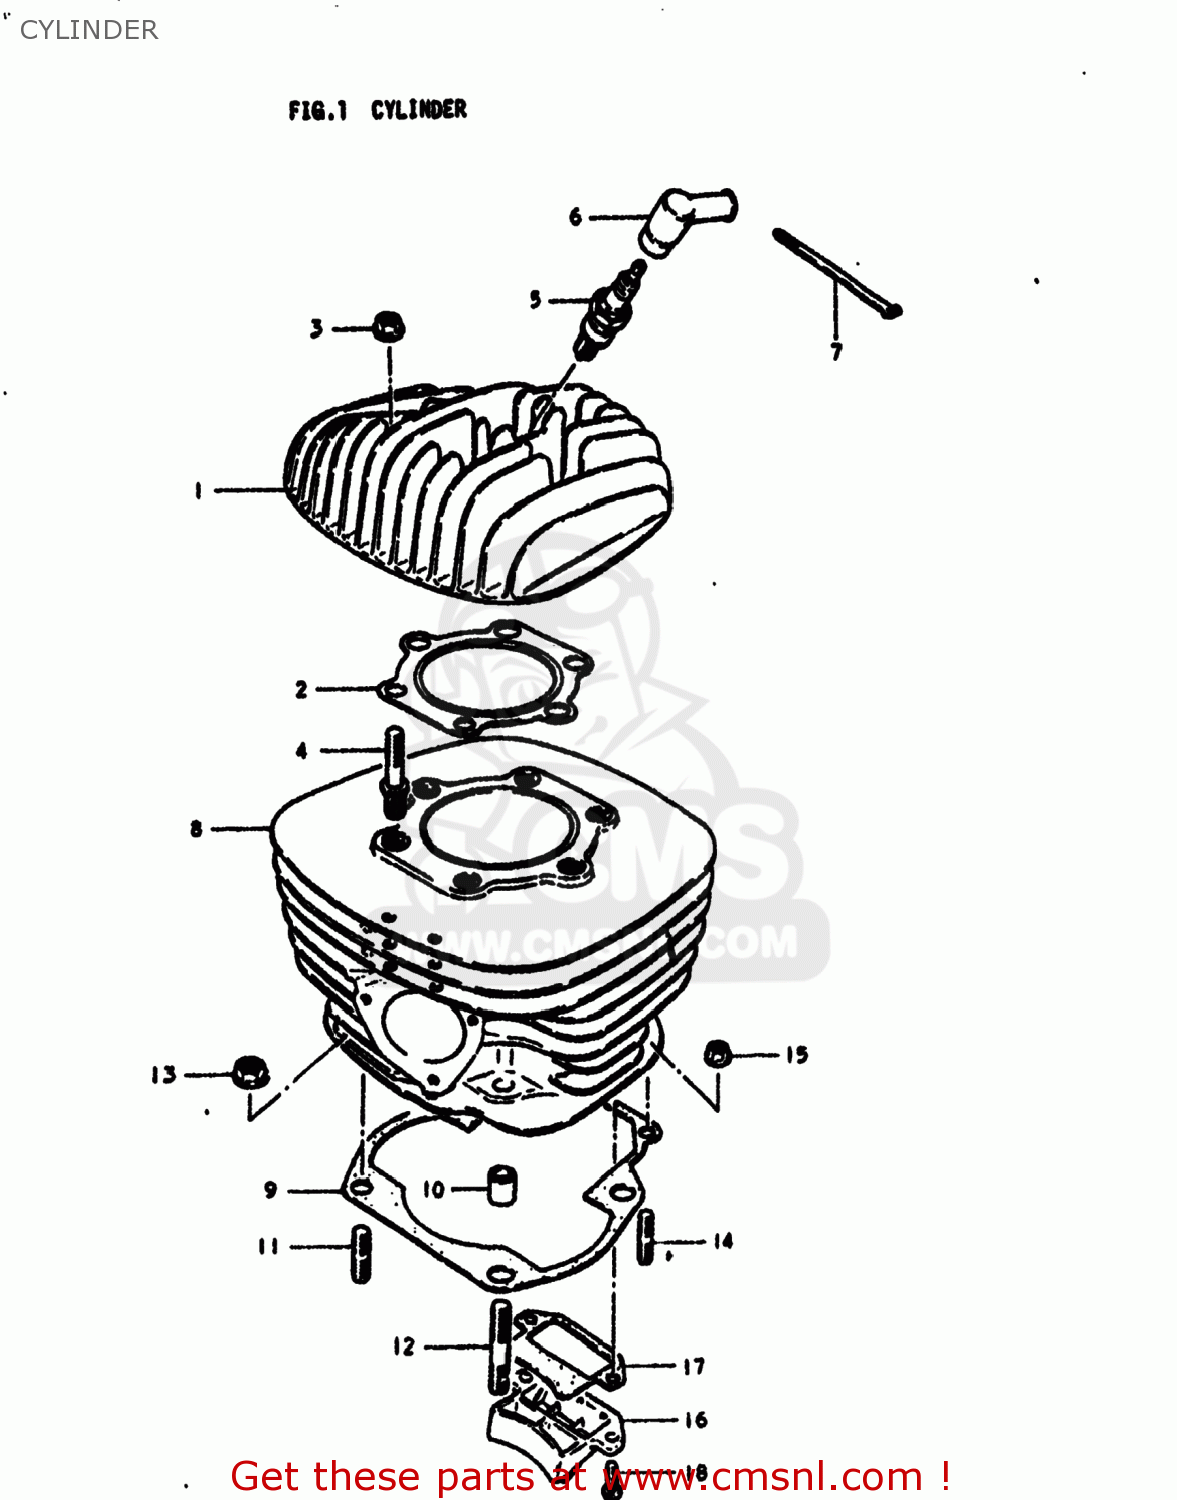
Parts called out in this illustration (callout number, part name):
1	HEAD,CYLINDER
2	GASKET,CYLINDER HEAD
3	NUT
4	STUD
5	SPARK PLUG
6	CAP,SPARK PLUG
7	CLAMP
8	CYLINDER
9	GASKET,CYLINDER (MCA)
10	PIN
11	STUD 10X30
12	STUD BOLT (L:45)
13	NUT
14	STUD 6X20
15	NUT
16	VALVE ASSEMBLY,REED
17	GASKET,REED VALVE (MCA)
18	SCREW
